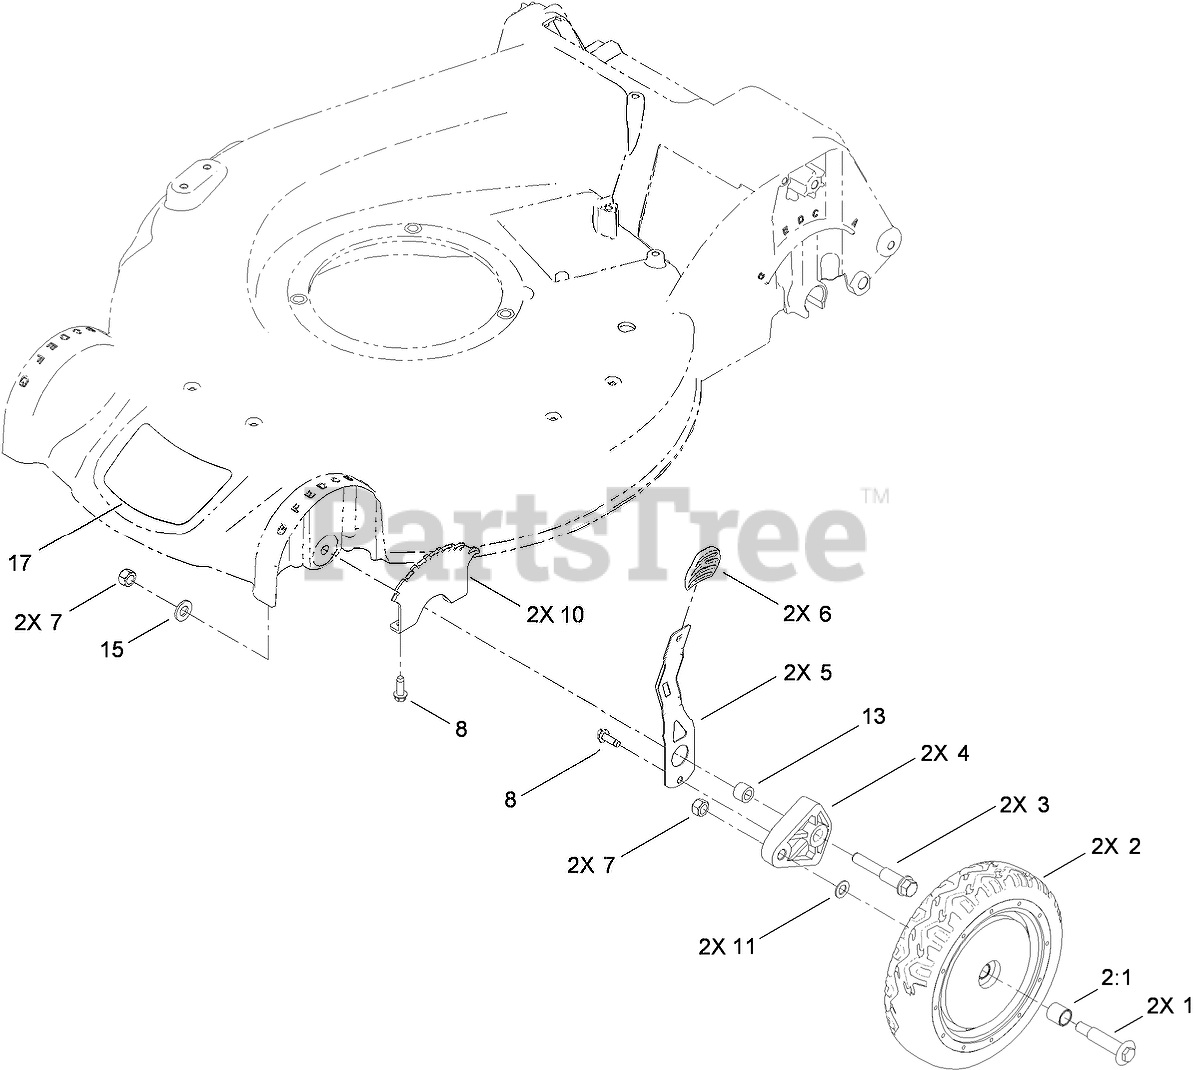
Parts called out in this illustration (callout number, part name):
1	BOLT-SHOULDER
2	8 INCH WHEEL ASM
2:1	BUSHING
3	SCREW-SHOULDER
4	ARM-PIVOT
5	ARM-SPRING
6	Knob-Lever, HOC
8	SCREW-HWHTF
10	PLATE-HOC
11	WASHER
13	SPACER-WHEEL
15	WASHER-FLAT
17	DECAL-HOUSING
